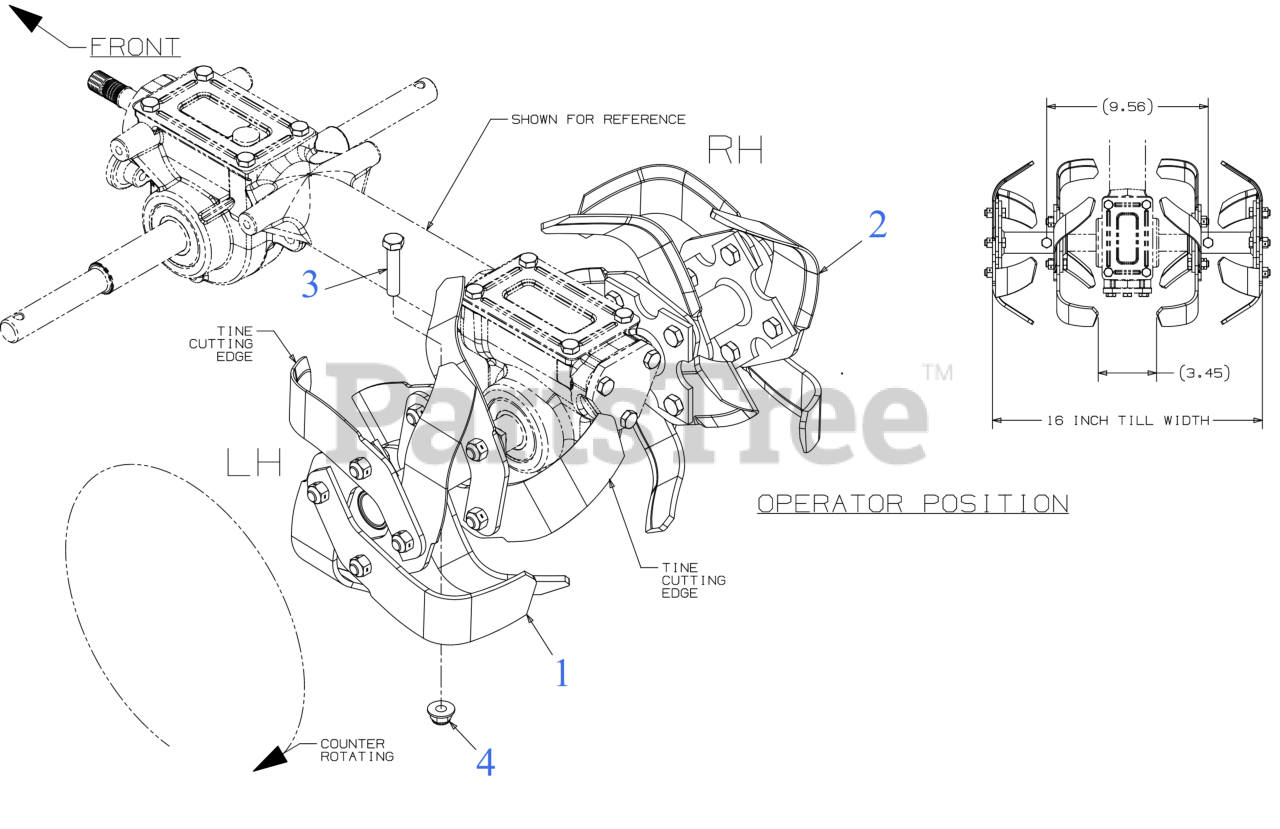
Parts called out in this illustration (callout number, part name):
1	SCREW 3/8-16 x 1 GR5
1	LOCK NUT 3/8-16
2	SCREW 3/8-16 x 1 GR5
2	LOCK NUT 3/8-16
3	HEX SCREW 3/8-16 x 1.75 GR5
